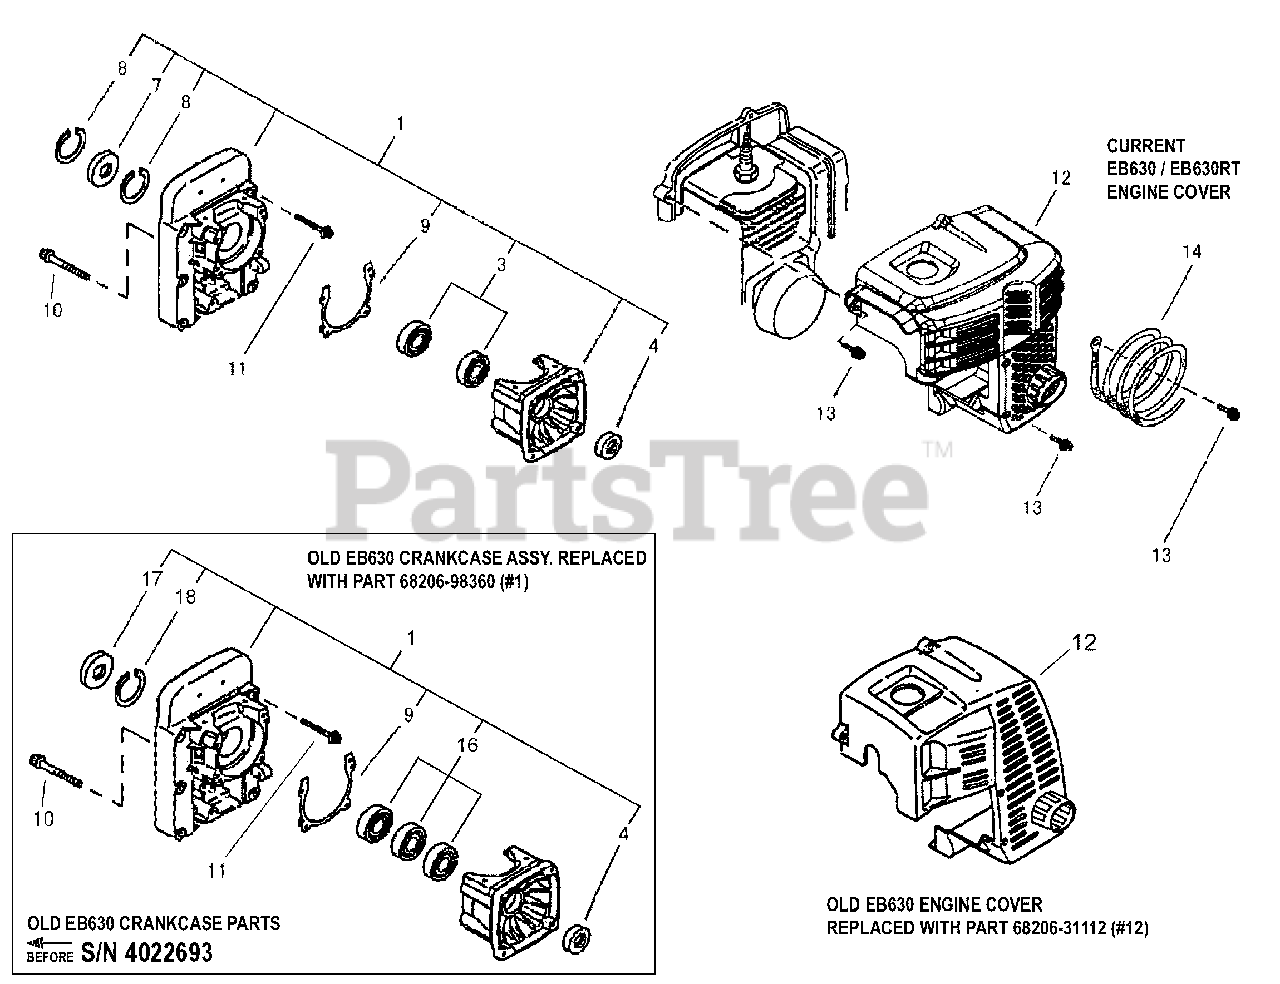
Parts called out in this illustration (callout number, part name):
1	CRANKCASE ASSY
3	BEARING, BALL
4	SEAL, OIL
7	SEAL, OIL
8	RING, RETAINING
9	GASKET
10	SCREW - 5X30
11	SCREW - 6X40
12	COVER, ENGINE
13	BOLT - 5X20
14	LEAD - ANTI-STATIC
